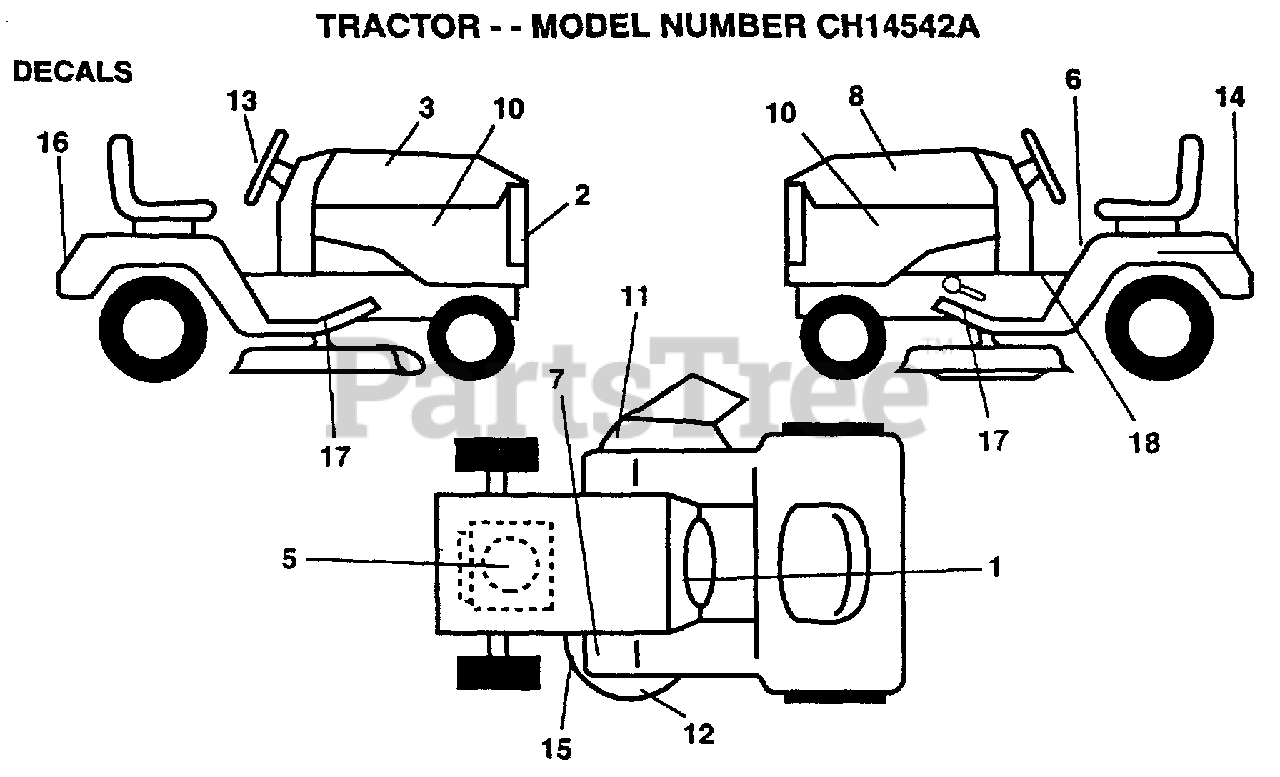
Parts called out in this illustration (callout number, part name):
1	DECAL.DASH.INSTR.
2	DECAL.GRILL
3	DECAL.HD.RH.WEED
5	DECAL, ENGINE
6	DECAL CAUTION
7	DECAL T
8	DECAL.HD.LH.WEED
10	DCL.PNL.SIDE.
11	"DECAL, WARNING"
12	DECAL.MOWER
13	DECAL.WHL.STRG.
14	DECAL
15	DECAL
16	DECAL.FENDER
17	"PAD,FOOTREST"
18	DECAL BRAK PARK
